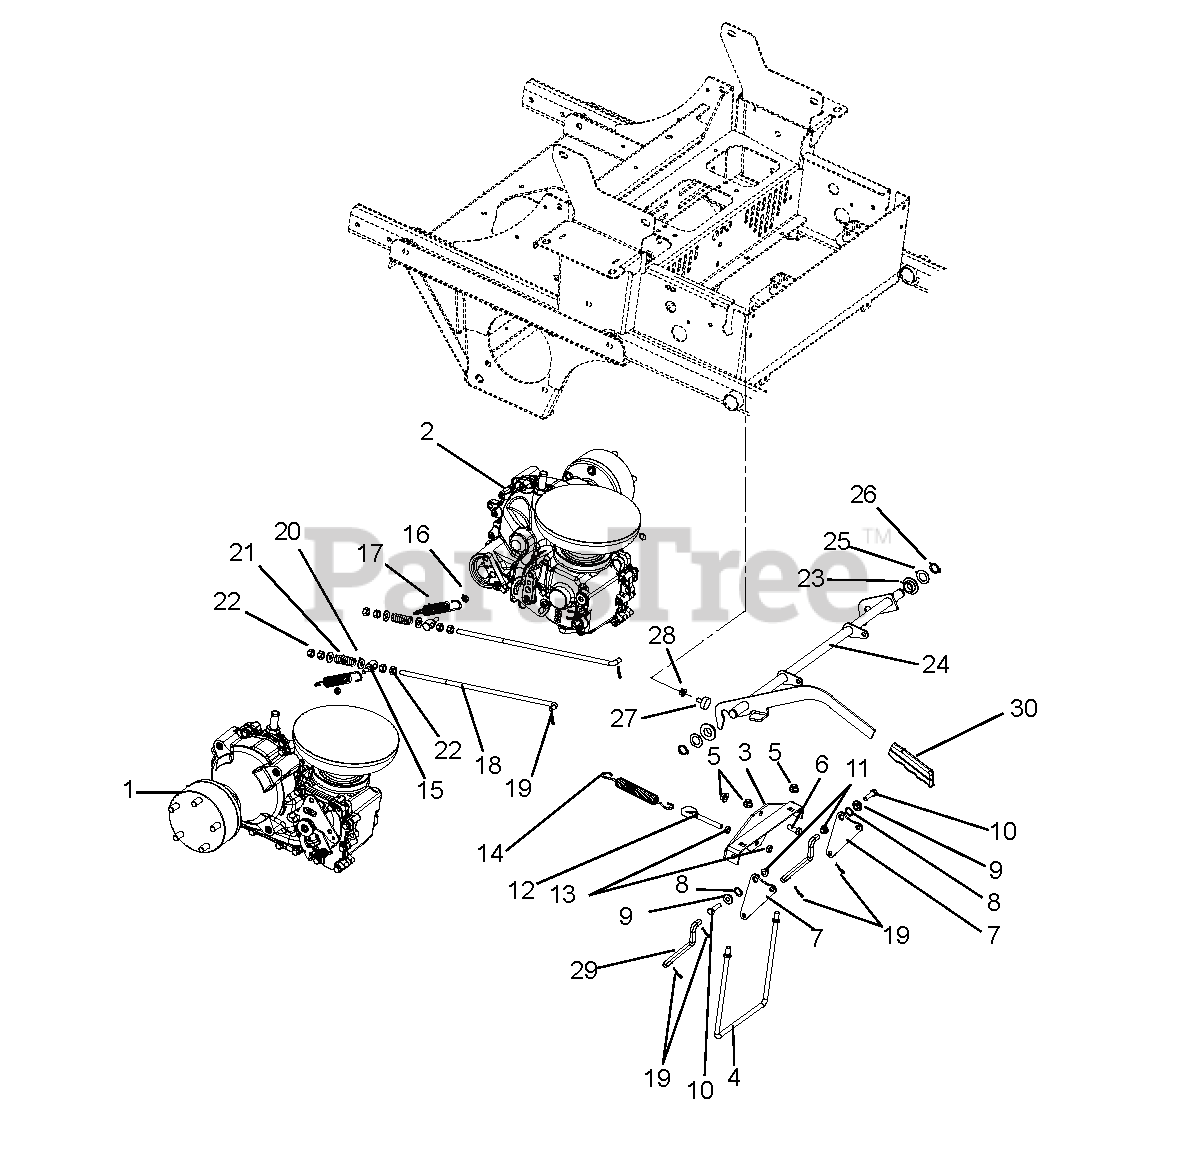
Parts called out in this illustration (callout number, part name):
1	Transmission, HG ZT-5400 Right Hand
2	Transmission, HG ZT-5400 Left Hand
3	Weldment, Spring Anchor Bracket
4	Rod, Brake Mounting
5	Nut, Locking Nyloc Flange .38-16 YWZC
6	Bolt, Hex .38-16 x 1.00 Grade 5 YWZC
7	Plate, Brake Pivot
8	Wave Washer .531 x .781 x .125FH
9	Bushing, Flange .32 x .500 x .344 x .880
10	Bolt, Hex .31-18 x 1.25 Grade 5 YWZC
11	Nut, Locking Nyloc Flange .31-18 YWZC
12	Bolt, Eye .375-16 x 2.50 YWZC
13	Nut, Hex Jam .375-16 YWZC
14	Spring, Extension
15	Trunnion, .38-16
16	Nut, Locking Center Jam .31-18 YWZC
17	Spring, Tension .105 x .85 x 5.00 WLD 40
18	Rod, Brake Adjustment
19	Pin, Hair
20	Washer, Flat Steel .38 x .875 x .083 YWZC
21	Spring, Compression .142 x .710 x 1.75
22	Nut, Hex .38-16 YWZC
23	Bushing, Flange .762 x 1.48 x .44 NYL
24	Weldment, Brake Interlock
25	Washer, Hardened Thrust .758 x 1.23 x .031
26	Ring, Retaining External .689 x .078
27	Bumper, Rubber
28	Nut, Spin Lock Flange .312-18 YWZC
29	Linkage, Brake Actuating
30	Grip, Parking Brake (Yellow)
